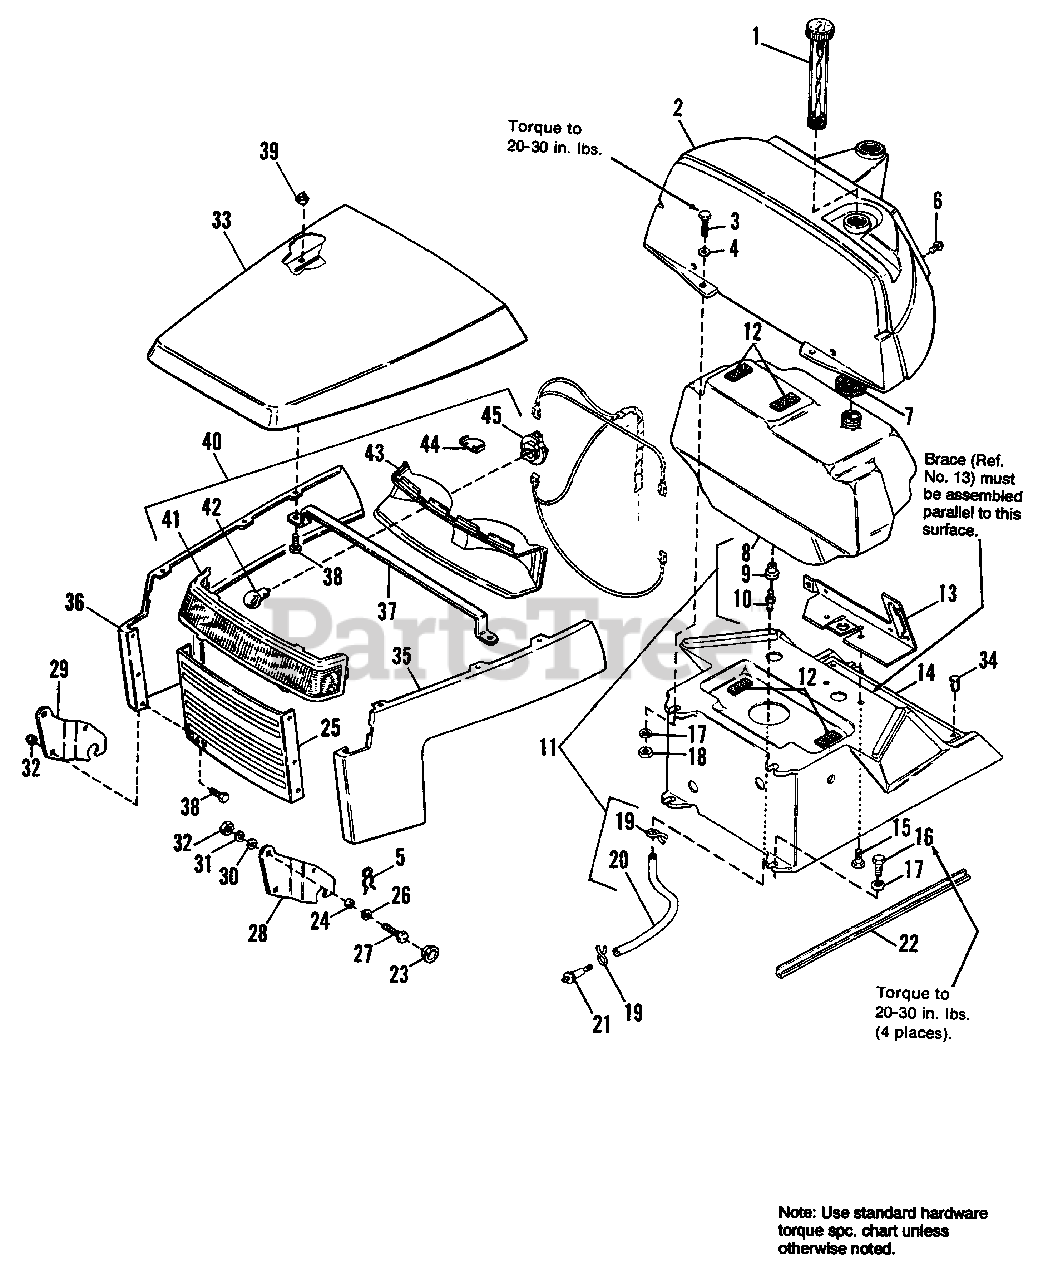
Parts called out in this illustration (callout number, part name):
1	CAP, Fuel Tank
2	DASHBOARD, Top
3	CAPSCREW, Hex, 1/4-20 x 1-1/4
4	WASHER, 1/4, std.
5	CUP, Hairpin
6	SCREW, Hex, Washer Hd., 1/4-20 x 5/8
7	WASHER, Foam
11	TANK ASSY., Fuel (Incl. Ref. Nos. 8, 9, 10, 19 (Qty. 1) & 20)
14	DASHBOARD, Bottom
15	SCREW, Taptite, 1/4-20 x 3/4
16	SCREW, Taptite, 1/4-20 x 1
17	LOCKWASHER, Dish, 1/4
18	LOCKNUT, Hex, 1/4-20
19	CLAMP, Hose
20	HOSE, Fuel (12" long)
21	FILTER, Fuel
22	EDGING, Lower Dash
23	SPACER, Hood
25	GRILLE
26	PIVOT, Hood
27	CAPSCREW, Hex Hd., 5/16-18 x 1-1/4
28	HINGE, L.H.
29	HINGE, R.H.
30	WASHER, Plain 5/16
31	LOCKWASHER, 5/16
32	NUT, Hex, 5/16-18
34	CLIP, Canoe
35	SIDE PANEL, L.H.
36	SIDE PANEL, R.H.
37	BAR-TIE, Hood
38	SCREW, Hex, Whizlock, 1/4-20 x 5/8
39	NUT, Hex, Nylon-lock, 1/4-20
40	HEADLIGHT ASSY. (Incl. Ref. Nos. 41-45)
41	LENS, Headlight
42	BULB, Headlight, 12.8V
43	BEZEL Headlight
44	HEAT SHIELD, Headlight
45	SOCKET, Bulb, Headlight
